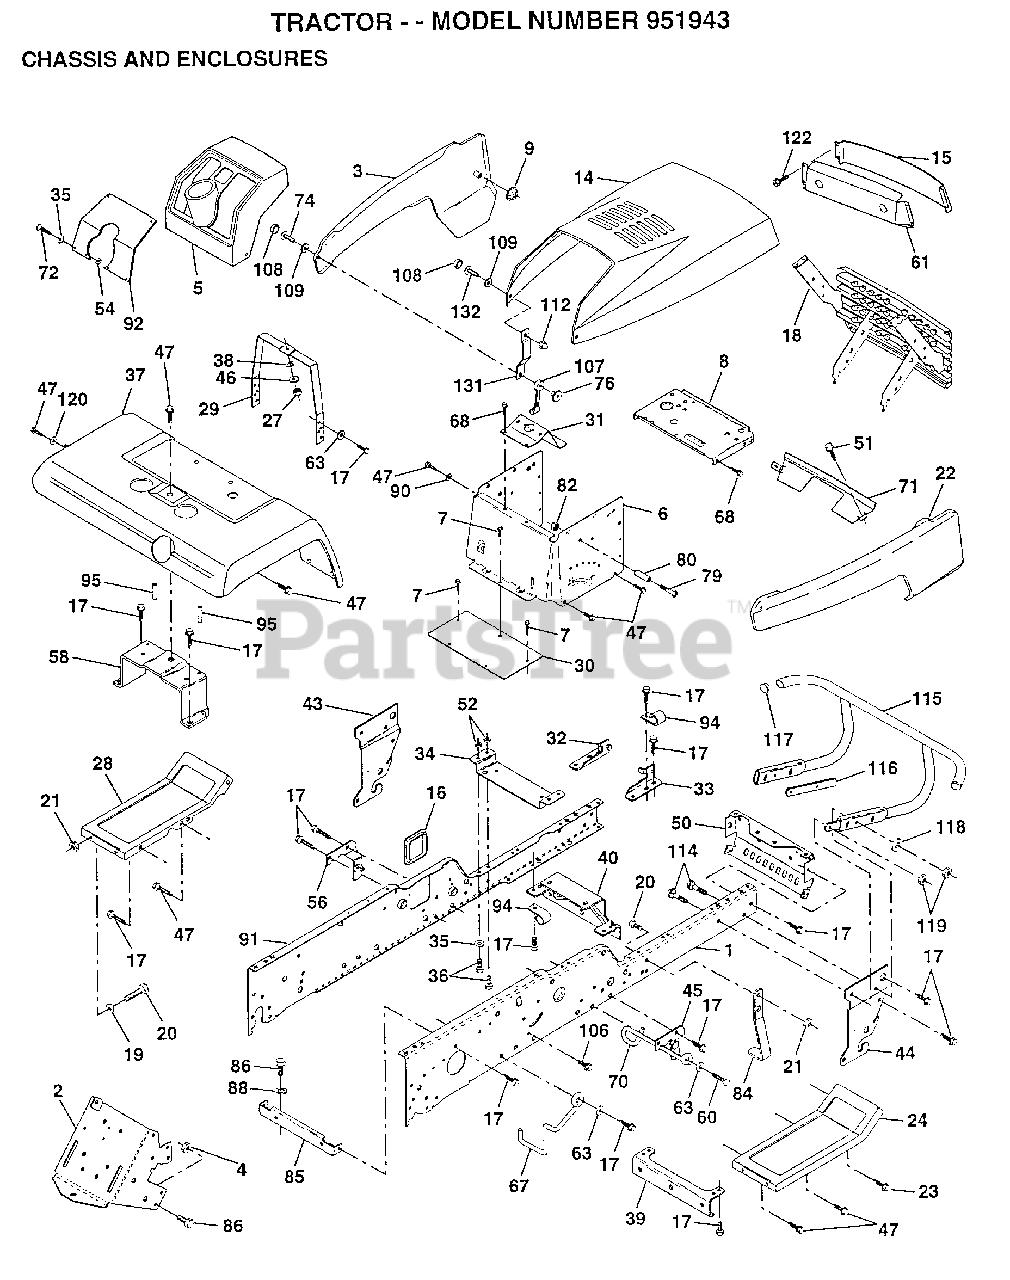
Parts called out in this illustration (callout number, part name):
1	"RAIL,FRAME RH"
2	DRAWBAR GT
3	PANEL ASM SIDE LH
4	NUT GTV
5	DASHBOARD BLACK
6	"DASH AS.,LOWER"
7	SCREW
8	SUPPORT.DASH.BTRY
9	PAL NUT LT
15	LENS.BAR.CLEAR
16	COVER ACCESS
17	SCREW
19	WASHER
20	BOLT
23	SCREW GTV
24	FOOTREST.RH.LT/GT
26	SCREW
28	FOOTREST.LH.LT/GT
29	DASH.SUPT.YP/HUSQ
30	SADDLE.SCR.6SP
31	BRAKET.SUPT.STEER
32	BRACKET ASM FRAME
33	BRACKET ASM FRAME
34	BRACKET.ENG.SUPT.
35	WASHER
36	BOLT
37	FENDER
38	LOCKWASHER
39	BRACKET.AXLE.FRT.
43	BRACKET.SUS.FT.LH
44	BRACKET.SUS.FT.RH
46	WASHER PM
47	SCREW LT
50	BRACKET.CHASSIS.
51	SCREW CRT
58	BRKT.ASM.FENDER
60	SCREW
61	BEZEL.ASM.
63	WASHER
67	GUIDE BELT TRANS
68	SCREW LT
70	GUIDE.BELT.MID.SP
71	STRAP.GRILLE.PNT.
72	SCREW
74	SCREW
76	WELDNUT
79	SCREW
80	SPACER LT
84	STOP.OVER.CENTER
85	BRACKET.SUPT.TRAN
86	BOLT
88	LOCKWASHER
90	LOCKWASHER
91	"RAIL,FRAME LH"
92	PLATE YP SLKSCR
93	SCREW LT
94	CLIP GTV
95	NUT-PUSH YT
107	HOOD LATCH T
108	SNAP CAP LT
109	WASHER LT
112	ACORN NUT RB
114	BOLT.3/8-14X1.25
115	BUMPER.ASM
116	BRACKET.EXT.BUMP.
117	PLUG.PLASTIC
118	WASHER
120	WASHER HYT
131	BKT.SPT.HOOD/PANL
132	SCREW.10-24X3/8.
